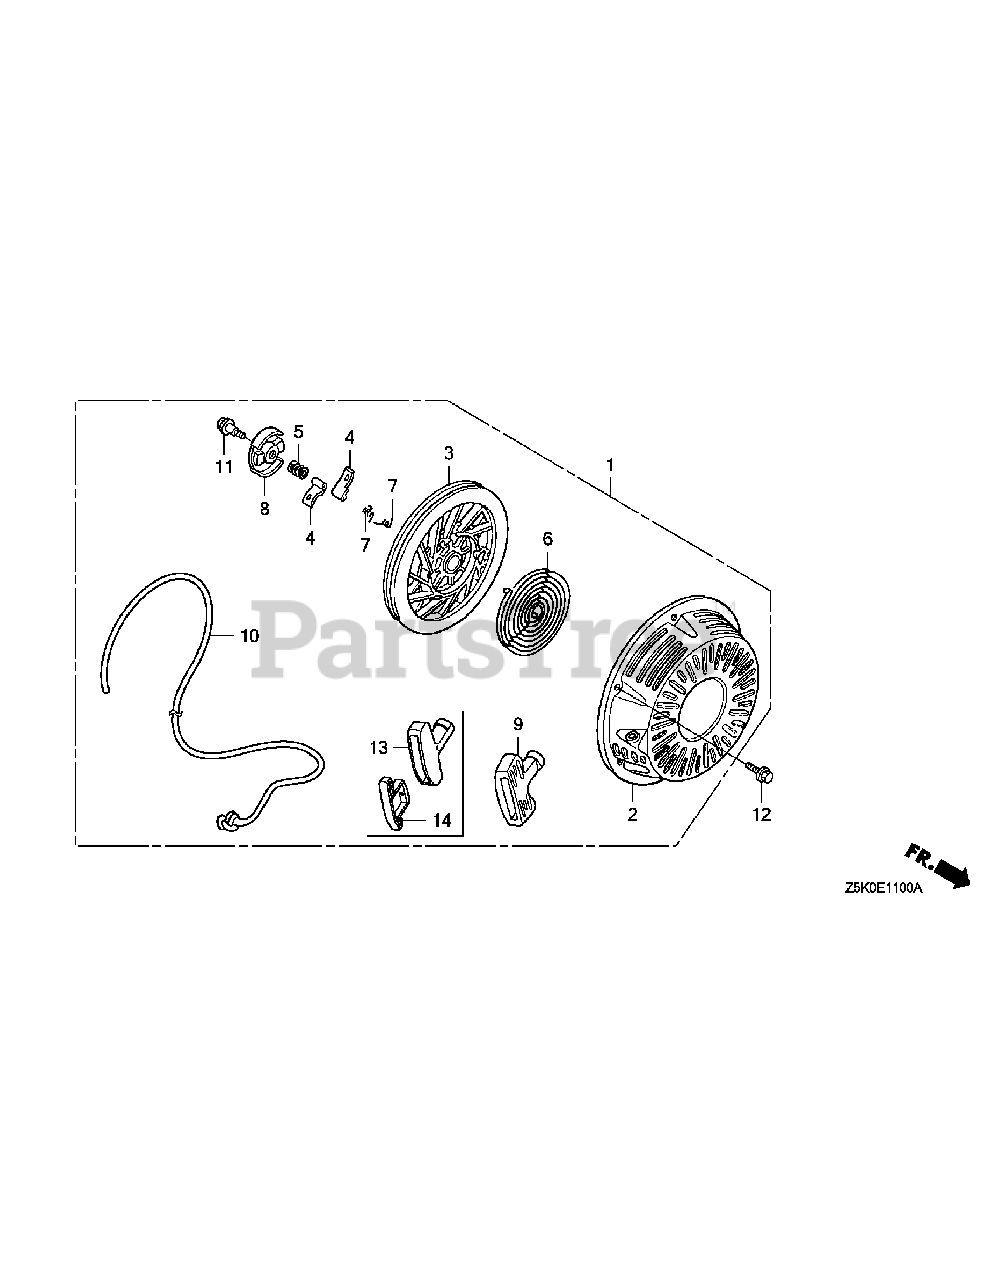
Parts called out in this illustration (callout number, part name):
1	Assembly, Recoil Starter
2	Case Comp., Recoil Starter
3	Pulley, Recoil Starter
4	Ratchet, Starter
5	Spring, Friction
6	Spring, Starter Return
7	Spring, Ratchet
8	Retainer, Spring
9	Grip, Starter
10	Rope, Recoil Starter
11	Screw, Center
12	Bolt, Flange, 6X10
13	Grip, Starter
14	Grip, Reinforcement
